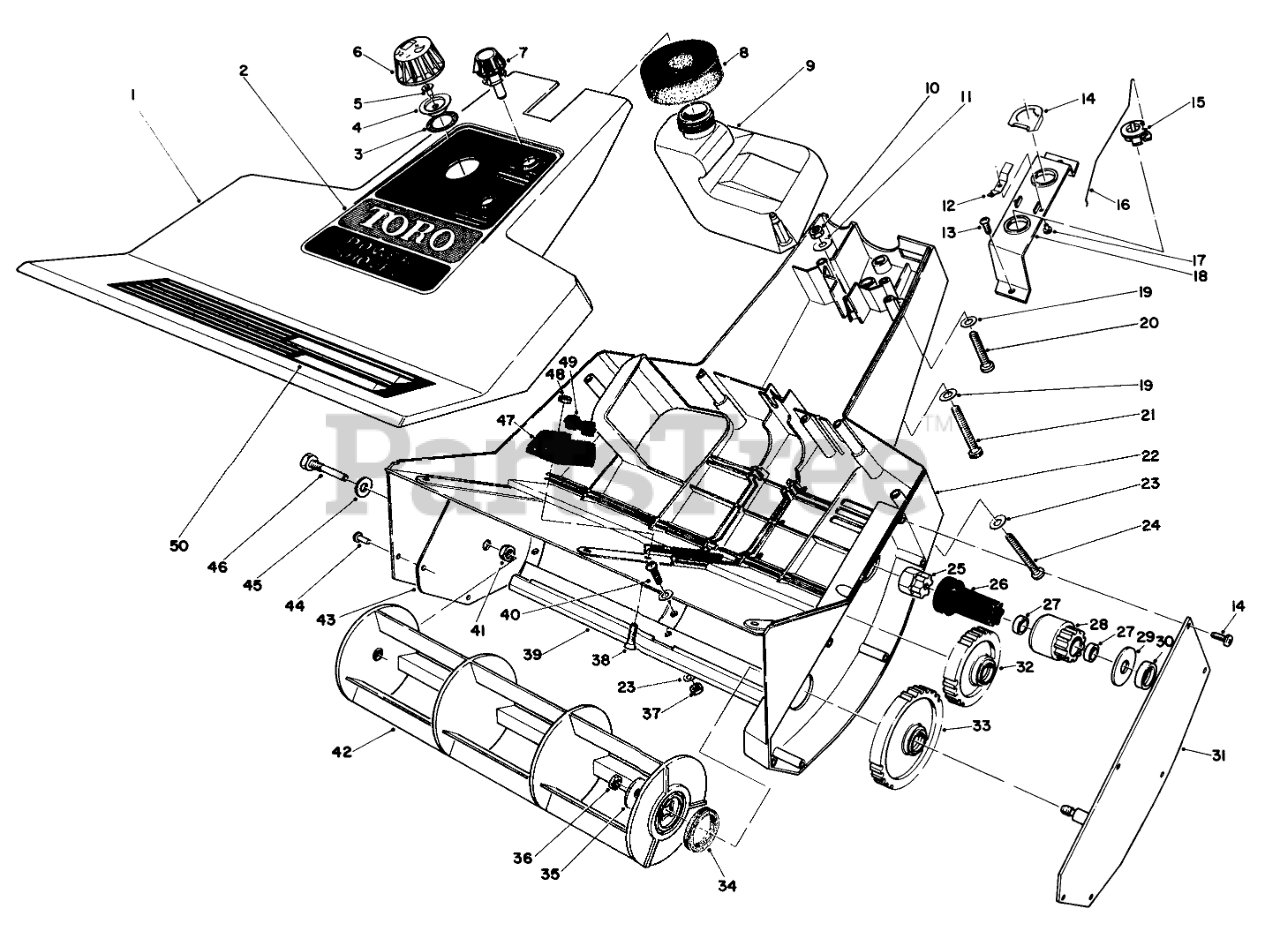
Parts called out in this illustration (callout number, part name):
1	Insert-Shroud Assembly (Incl. Ref. #50)
2	CONTROL DECAL
3	Gasket
4	Insert
5	Valve
6	Gas Cap Assembly (Incl. Ref. #3-5)
7	Knob-Control
8	FOAM PAD
9	GAS TANK
11	WASHER
12	CONTACT SWITCH
13	Screw-Self Tapping
14	SWITCH ACTUATOR
15	CONTROL
16	CHOKE LINKAGE
17	.125 X 1/8 POP RIVET
18	Bracket-Controls
19	WASHER-FLAT
20	SCREW-HSH
21	SCREW-HSH
22	Housing (Incl.Ref. #43 & 44)
23	WASHER-FLAT
24	MACH SCREW 10-24 2.25 L
25	Adapter-Crankshaft
26	DRIVE COUPLING
27	Bearing
28	Gear Assembly-Drive (Incl. Ref. #27)
29	Washer-Thrust
30	Spacer Gear
31	Gear Carrier Plate
32	Gear Assembly-Idler
33	Gear Assembly-Rotor
34	FELT WASHER
35	WASHER-FLAT
36	NUT-LOCK, NI
37	NUT-LOCK
38	Screw-Machine Slotted Flat Hd.
39	SCRAPER
40	SCREW-PPH
41	3/8 24 JAM NUT
42	ROTOR
43	Plate Housing Reinforcement
44	RIVET-POP
45	WASHER-FLAT
46	ROTOR PIN
47	Mount-Engine Upper
48	NUT-LOCK, NI
49	Mount-Rubber Isolator
50	Decal-Warning
